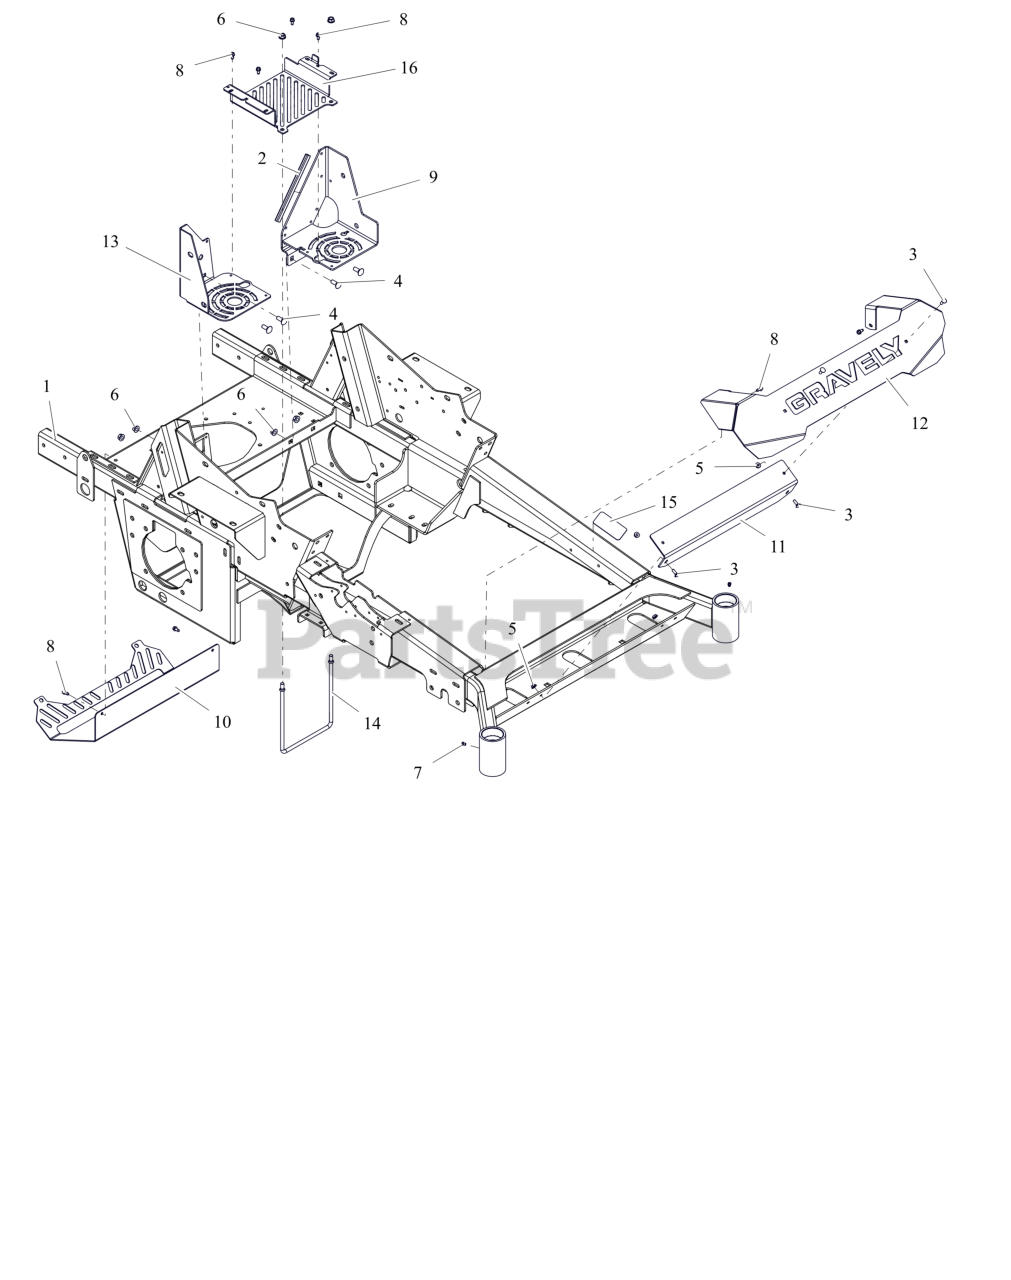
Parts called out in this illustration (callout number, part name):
1	WLDMT, 48", 52", 60" FRAME (RED)
2	STRIP, COWL
3	BLT, RHSN .25-20X.750 G5 ZCC
4	BLT, RHSN .38-16X1.00 G5 ZCC
5	NUT-LK-CTR-FLG .25-20 ZC120
6	NUT-LK-CTR-FLG .375-16 GF ZCC
7	FTG, .25-28 FLUSH MNT GREASE
8	SCR-TAP .25-20X.50 HWH ZCC
9	GUSSET-LH BATTERY TRY/ROPS-RED
10	GUARD, MUFFLER (BLACK)
11	BRKT, FRONT BUMPER MTG/BACKER (BLACK)
12	BMPR, 48" 52" 60" FRONT (RED)
13	GUSSET- FAN GUARD/ROPS - RED
14	ROD, BRAKE MTG
15	KIT, PT300-600 ANTI-SKID Tape
16	TRAY- BATTERY
